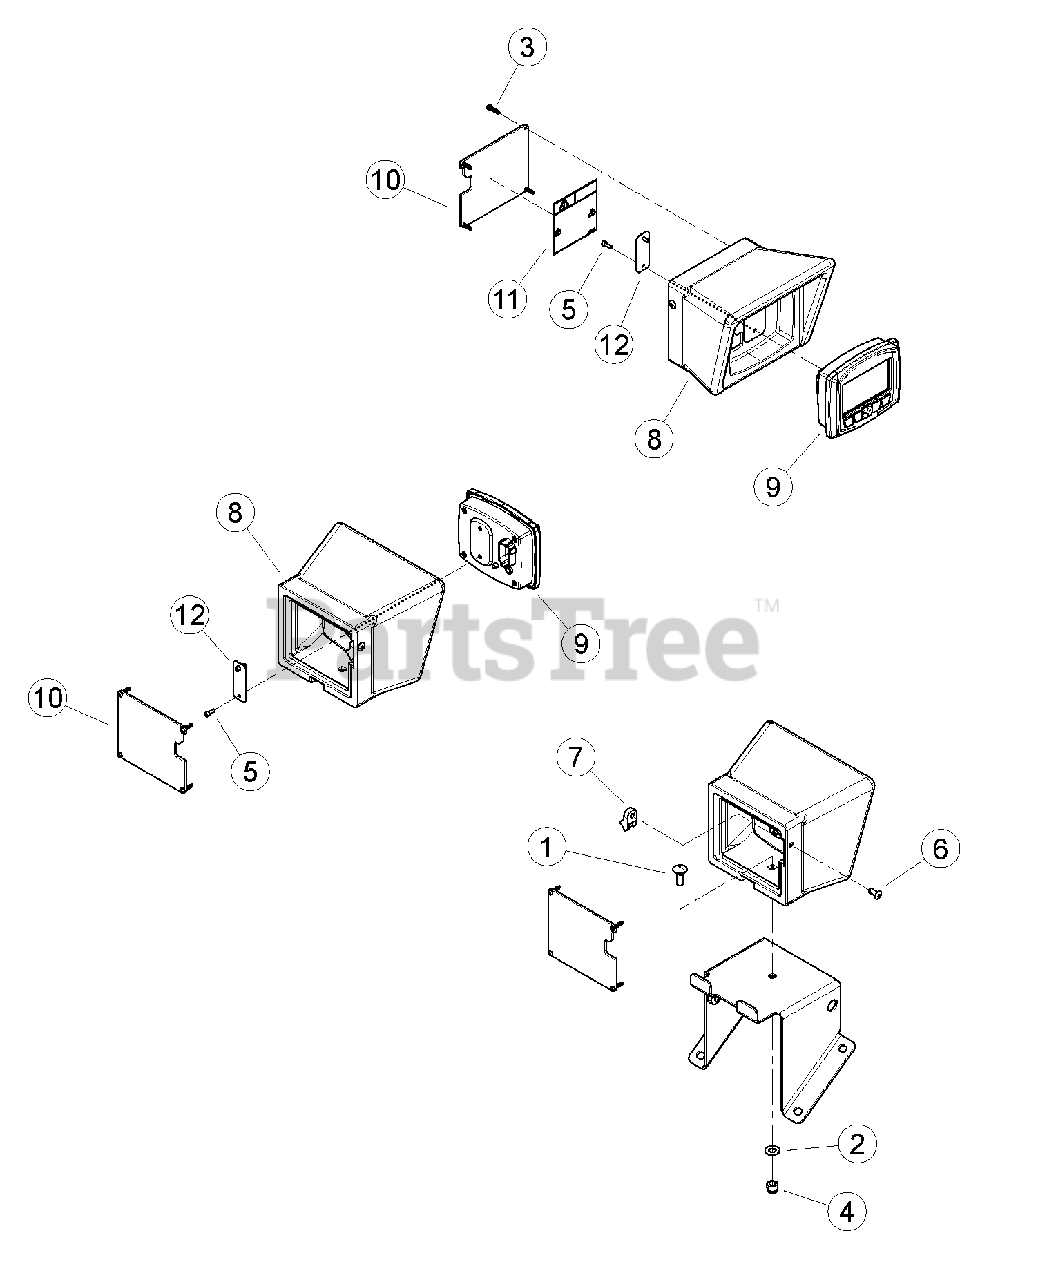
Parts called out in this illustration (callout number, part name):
1	BOLT, 3/8 X 1" GR5 CRG NC ZP
2	WASHER, 3/8" SAE FLAT ZP
3	SCREW, 10-16 3/4 LONG FOR PLASTIC
4	NUT, 3/8" NE NYLOCK ZP
5	SCREW, #8-32 X 1/2 SKT HD CAP
6	RIVET, AL BLIND 1/4 X 3/4 DOME HEAD
7	CLAMP, CABLE MOUNT
8	ENCLOSURE, CONTROLLER
9	CONTROLLER, CL-709-100 MASTER
10	ASSEMBLY, ENCLOSURE COVER WITH DECAL
11	DECAL, DDC MOUNTING INFO
12	PLATE, DDC WASHER
